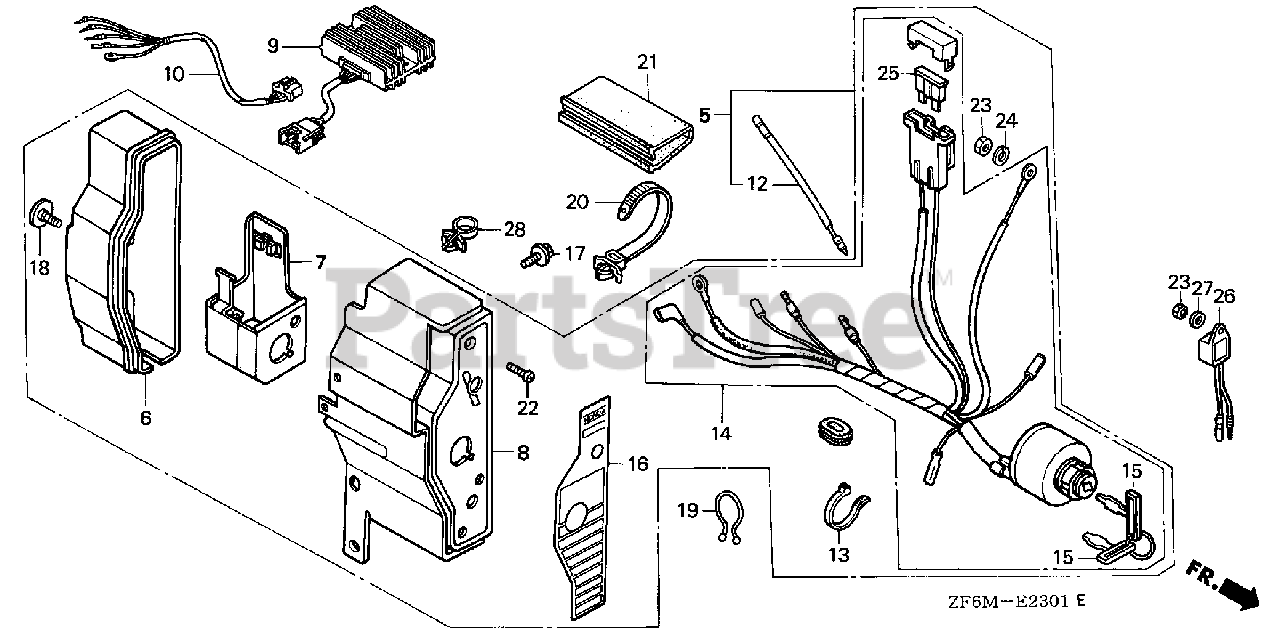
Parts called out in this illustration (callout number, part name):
5	BOX ASSY., CONTROL (EXP-ALT,18A) *R8* (BRIGHT RED)
6	CASE, CONTROL
7	BRACKET, CASE MOUNTING
8	PANEL, CONTROL *R8* (BRIGHT RED)
12	SUB-HARNESS
13	BAND
14	SWITCH ASSY., COMBINATION (18A-CHARGE)
15	KEY
16	MARK, CONTROL BOX (EXTERNAL-REGULATOR)
17	BOLT, FLANGE (6X12) (CT200)
18	SCREW, SPECIAL (6X12)
19	CLIP, PURSE LOCK
20	STRAP, CABLE (118MM) *NH1L* (BLACK)
21	TUBE, FASTENER (30)
22	SCREW, PAN (4X12)
23	NUT, HEX. (4MM)
24	WASHER, SPRING (4MM)
25	FUSE, BLADE (25A)
26	ALERT UNIT, OIL
27	WASHER, PLAIN (4MM)
28	HOLDER, STOP SWITCH WIRE
